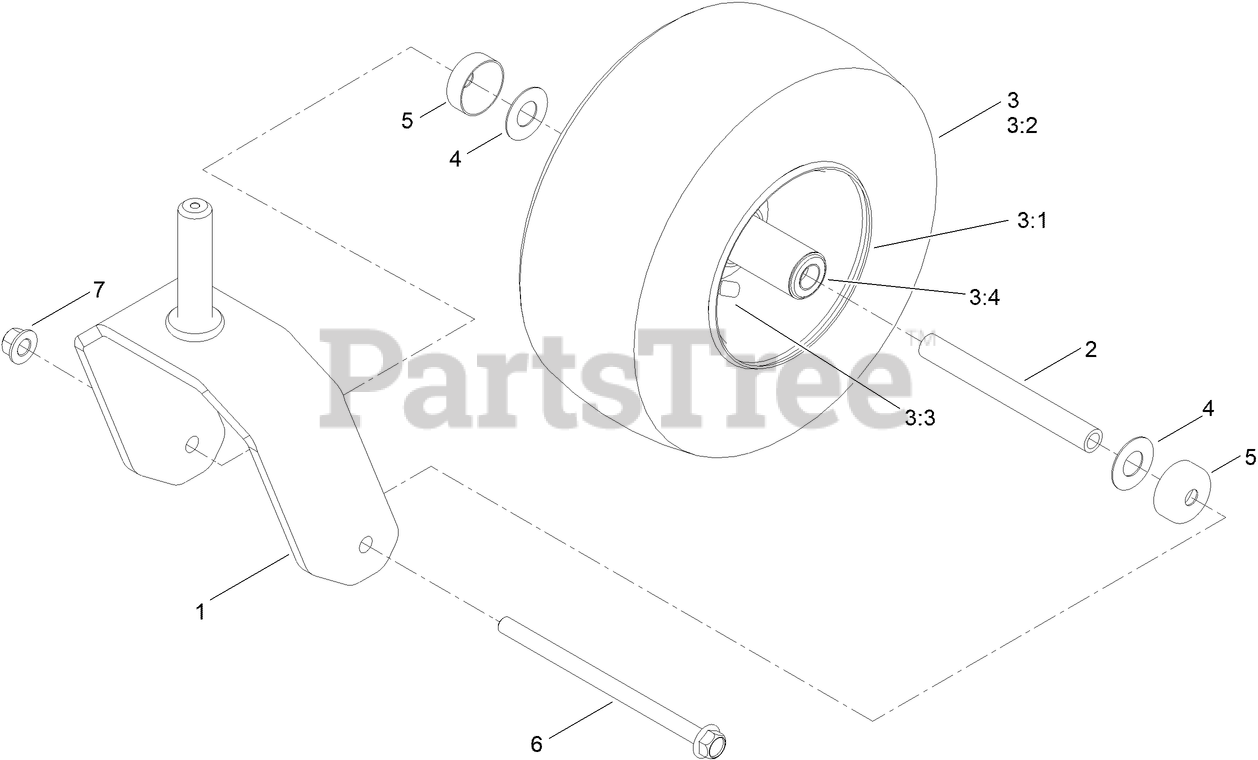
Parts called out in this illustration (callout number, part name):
1	CASTER-FORK [BLACK]
2	SPANNER-WHEEL
3	TIRE AND WHEEL ASM
3:1	RIM-6"
3:4	BEARING
4	WASHER
5	GUARD-SEAL
6	SCREW-HHF
7	NUT-LOCK
